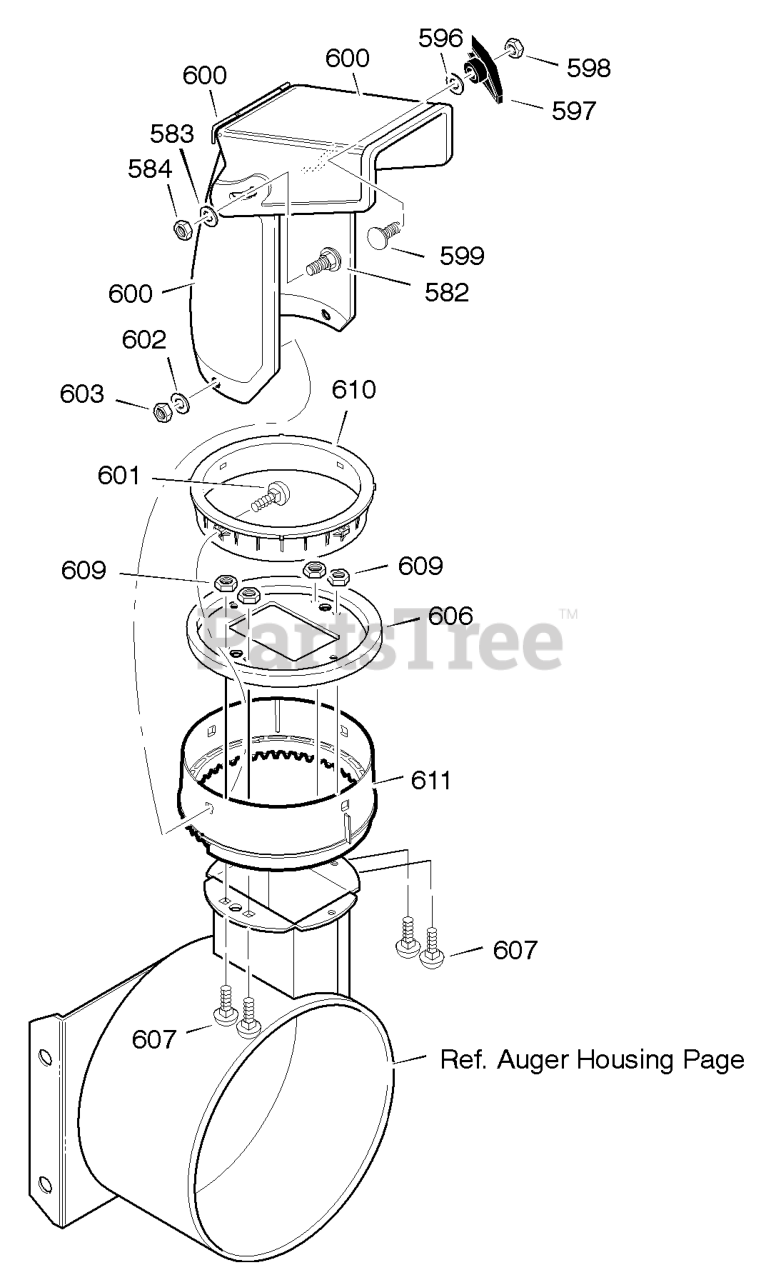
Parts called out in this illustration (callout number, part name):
582	SCREW, 5/16-18 x 1.00
583	WASHER, FLAT
584	NUT, 5/16-18
596	WASHER
597	KNOB, T 3.00
598	NUT, 5/16-18
599	BOLT, 5/16-18 x 1.50
600	CHUTE ASSEMBLY
601	BOLT, 5/16-18 x 1.00
602	WASHER, FLAT
603	NUT, 5/16-18
606	CHUTE COLLAR
607	SCREW, 1/4-20 X 0.75
609	NUT, 1/4-20 HEX NYLOCK
610	RETAINER RING INNER
611	RETAINER RING OUTER
